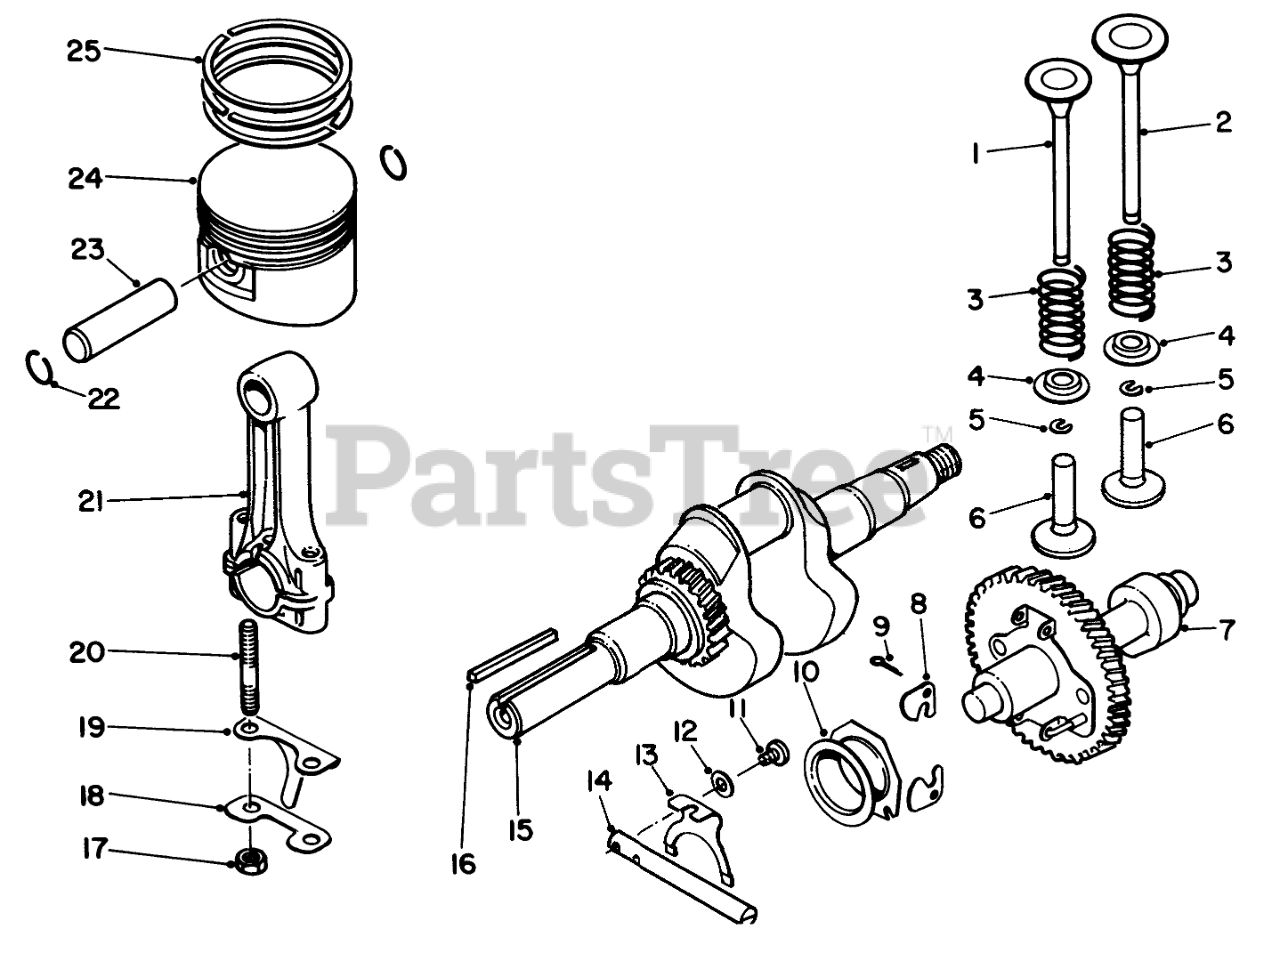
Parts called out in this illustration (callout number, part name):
1	Valve-Exhaust
2	Valve-Intake
3	Spring-Valve
4	Retainer
5	Cotter
6	Tappet (L:36.39)
7	Cam Shaft
9	Cotter Pin
10	Spacer
11	SCREW
12	Washer
13	Plate-Shift
14	Shaft-Throttle Return
18	LOCK PLATE
19	PLATE
20	Stud Bolt
21	Connecting Rod Assembly (Std.) (Incl. Ref. #17-20)
22	CIRCLIP
23	PISTON PIN
24	Piston Std.
25	Ring Set-Piston Std.
